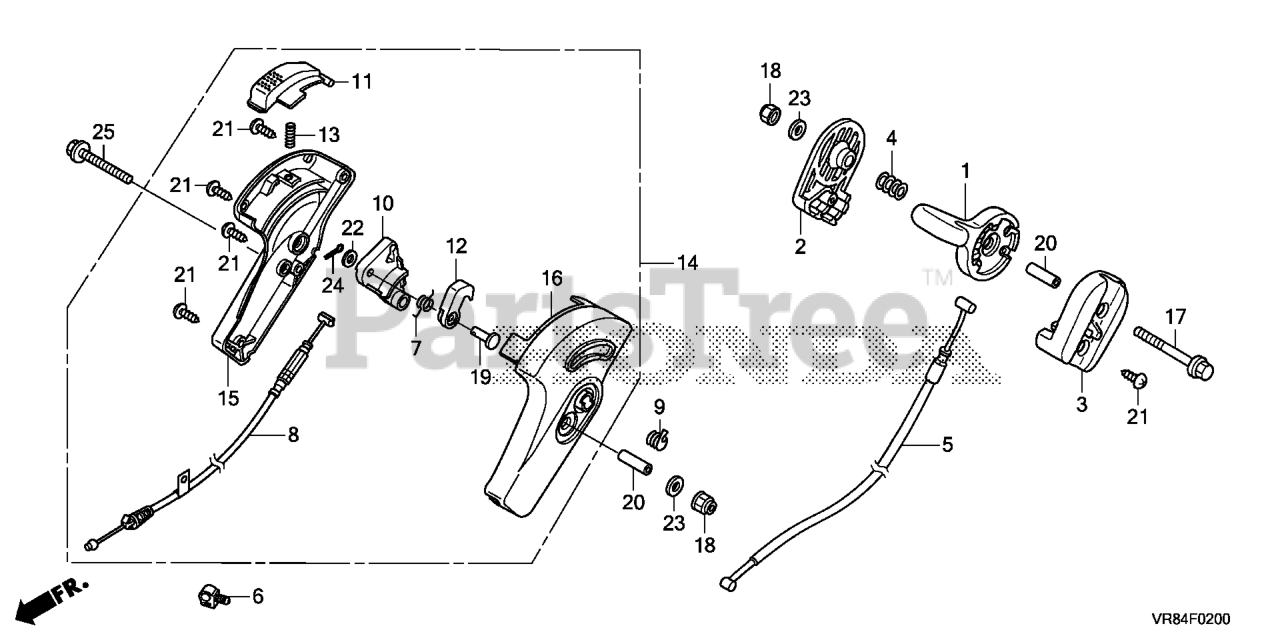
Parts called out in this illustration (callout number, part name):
1	LEVER, THROTTLE
2	CASE, R. THROTTLE LEVER
3	CASE, L. THROTTLE LEVER
4	SPRING, THROTTLE LEVER
5	CABLE, THROTTLE
6	HOLDER, WIRE
7	SPRING, LOCK LEVER RETURN
8	CABLE, ROTO-STOP
9	SPRING, R. STOP RETURN
10	ARM, ROTO-STOP CABLE
11	KNOB, PUSH
12	LEVER, LOCK
13	SPRING, LEVER RETURN
14	CONTROL ASSY., ROTO-STOP
15	CASE, ROTO-STOP (R)
16	CASE, ROTO-STOP (L)
17	BOLT, FLANGE (6X65)
18	NUT, NYLON LOCK (6MM)
19	PIN, CLUTCH LEVER
20	COLLAR, THROTTLE
21	SCREW, TAPPING (4X12)
22	WASHER, PLAIN (6MM)
23	WASHER, PLAIN (6MM)
24	PIN, LOCK (6MM)
25	BOLT, FLANGE (6X65)
